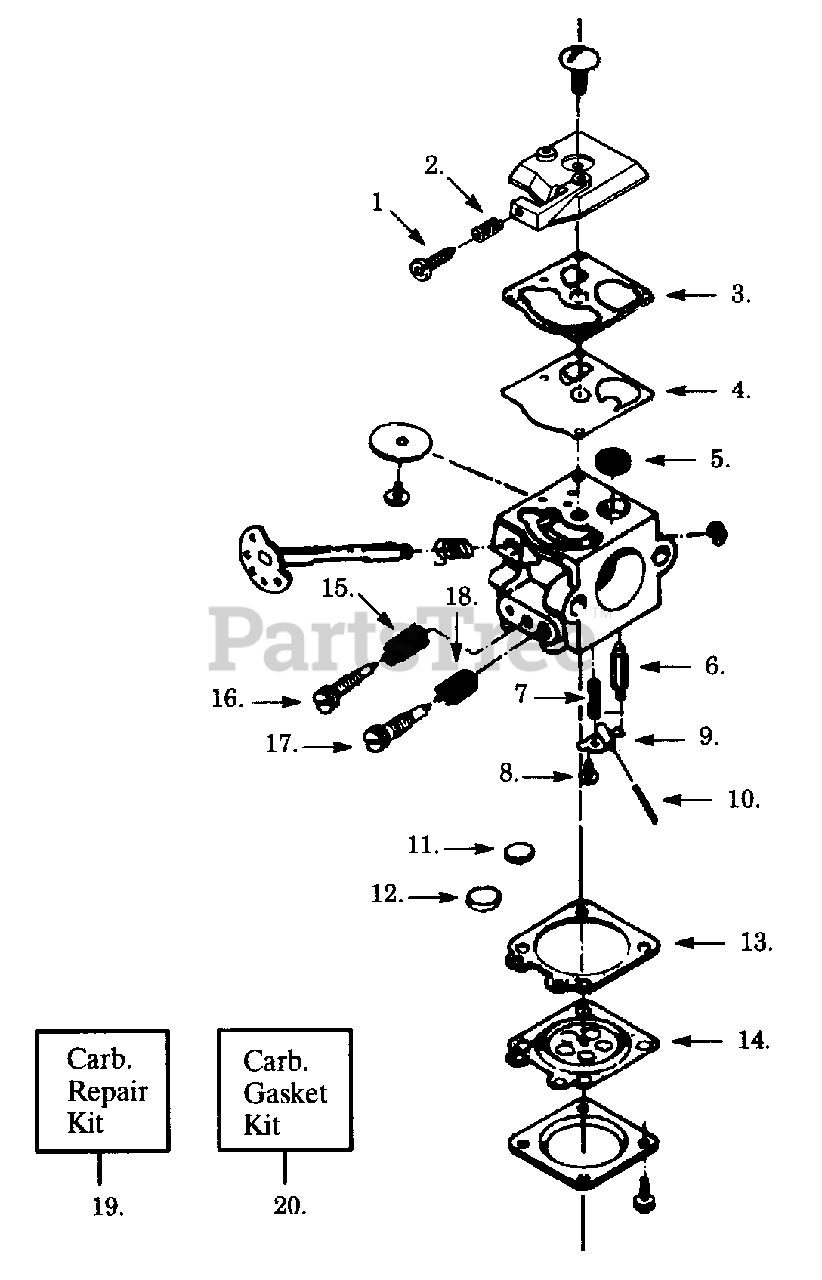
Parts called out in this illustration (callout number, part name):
1	Idle Speed Adj. Screw
2	Idle Speed Adj. Spring
3	Fuel Pump Gasket
4	Fuel Pump Diaphragm
5	Fuel Inlet Screen WT-3
6	Inlet Needle Valve
7	Metering Lever Spring
8	Metering Lever Pin Screw
9	Metering Lever
10	Metering Lever Pin
11	Welch Plug-5/16 Dia.
12	Welchg Plug-1/4 Dia.
13	Metering Diaphragm Gasket
14	Metering Diaphragm
15	Low Speed Mixture Needle Spring
16	Low Speed Mixture Needle
17	High Speed Mixture Needle
18	High Speed Mixture Needle Spring
19	Carb. Repair Kit
20	Carb. Gasket/Diaphragm
